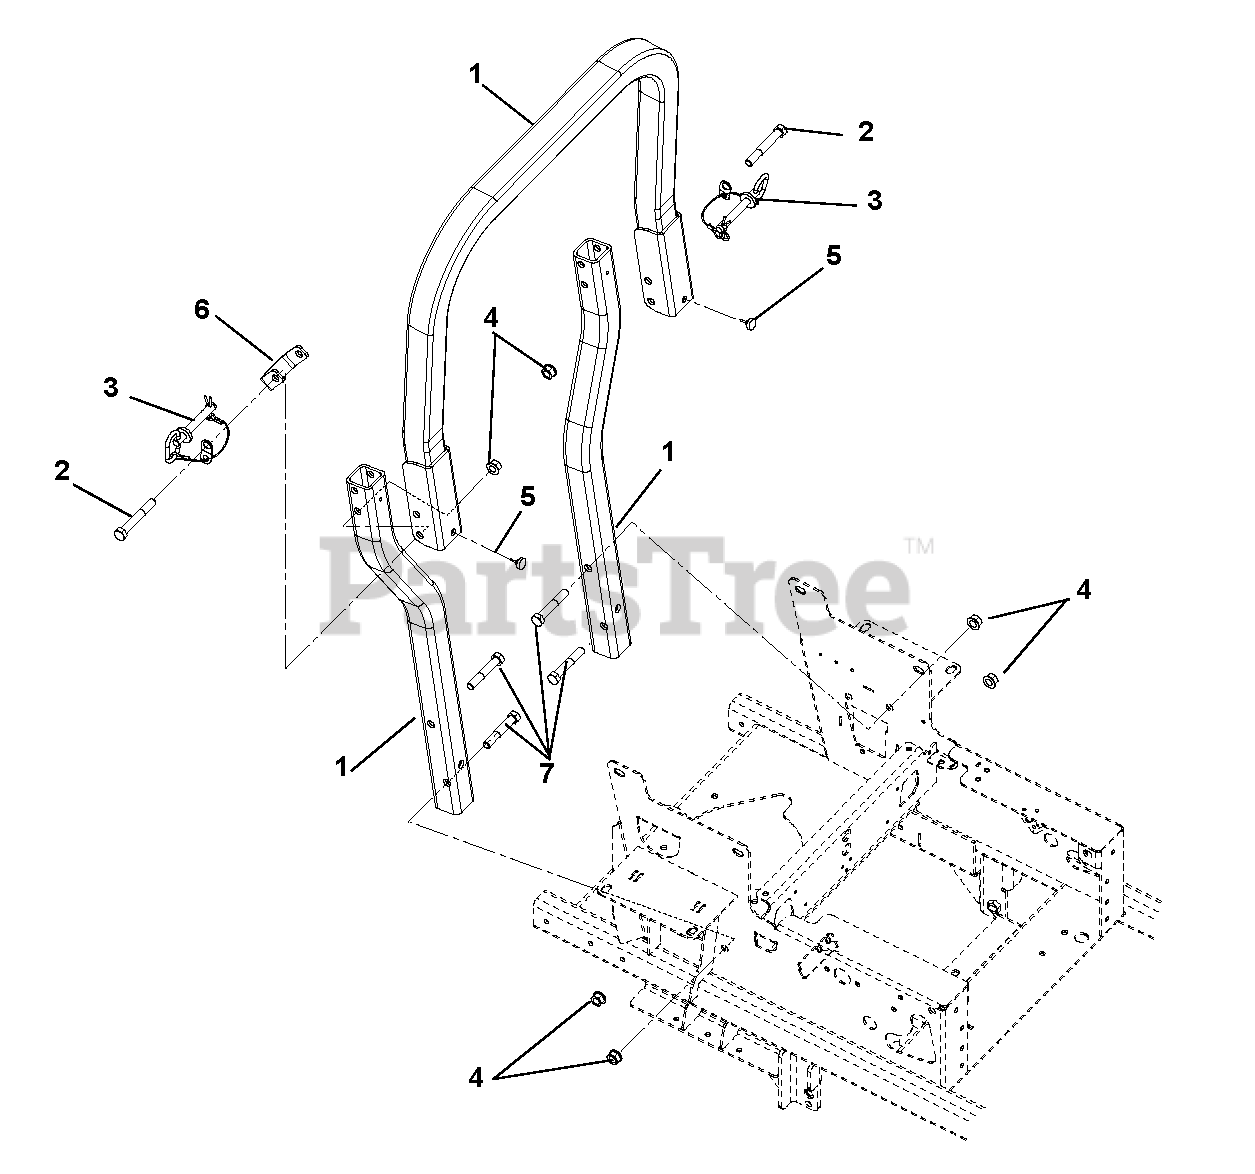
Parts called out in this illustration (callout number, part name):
1	ROPS, PT100 Replacement
2	Bolt, Hex .50-13 x 3.50
3	Assembly, ROPS Pin/Lanyard
4	Nut, Locking Top Flange .50-13
5	Bumper, ROPS Rubber
6	Bracket, ROPS Stop, Pro-Turn
7	Bolt, Hex .50-13 x 3.00
